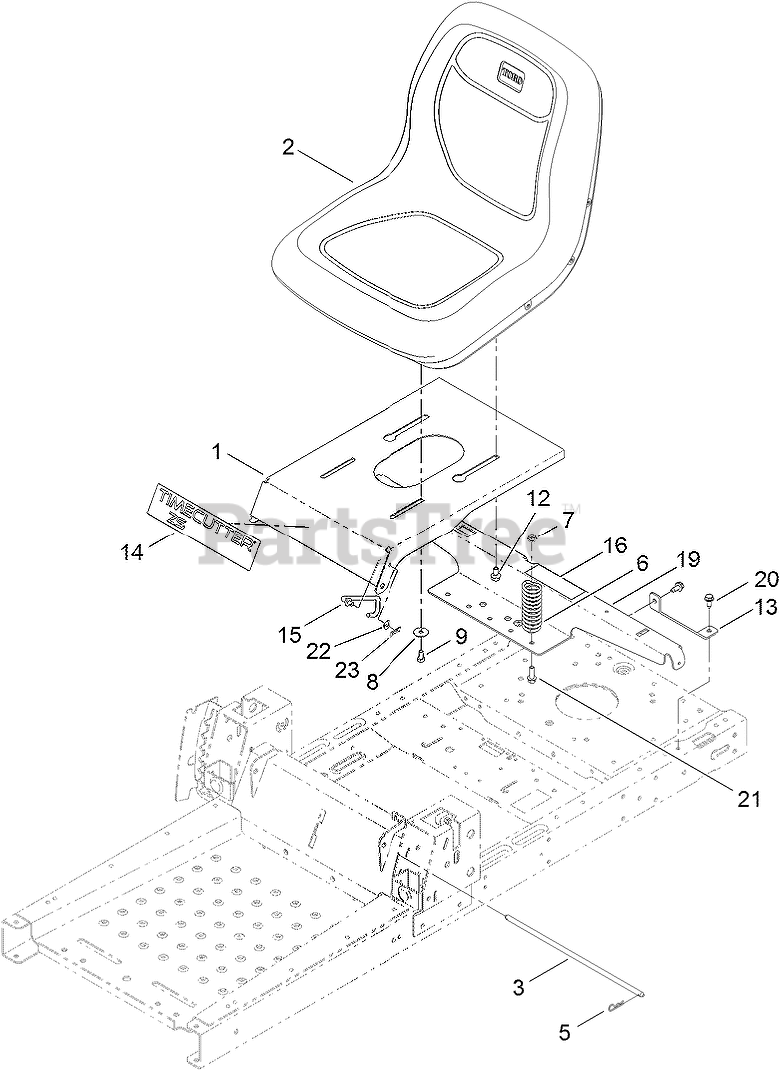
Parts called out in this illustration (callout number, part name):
1	PAN-SEAT
2	SEAT-18 INCH
3	ROD-PIVOT, NARROW
5	PIN-COTTER
6	SPRING-COMPRESSION
7	NUT-HF, NI
8	WASHER-PIVOT
9	SCREW-HH
12	BOLT-SHOULDER
13	SUPPORT-TANK, REAR
14	DECAL-TIMECUTTER
15	STOP-SEAT
16	DECAL-SERVICE, CE
19	SUPPORT-POD
20	SCREW-HWHTF
21	SCREW-HHF
22	WASHER-PLAIN
23	PIN-COTTER
